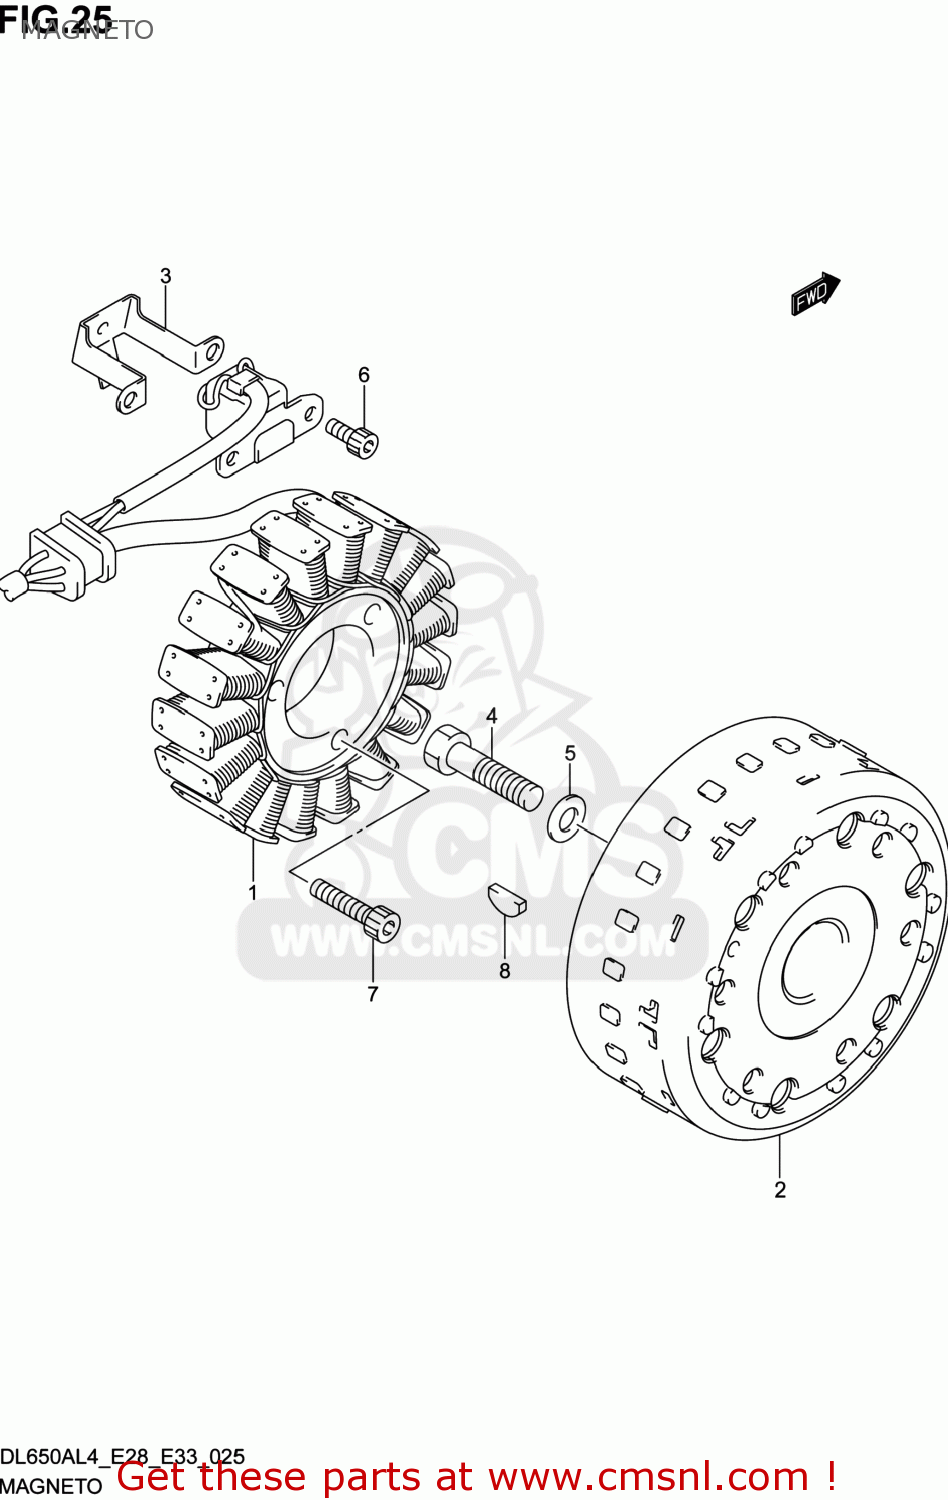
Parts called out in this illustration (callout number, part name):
1	STARTER ASSY
2	ROTOR ASSY
3	CLAMP,MAGNETO LEAD
4	BOLT(12X40)
5	WASHER(12X30X3)
6	BOLT
7	BOLT
8	KEY
